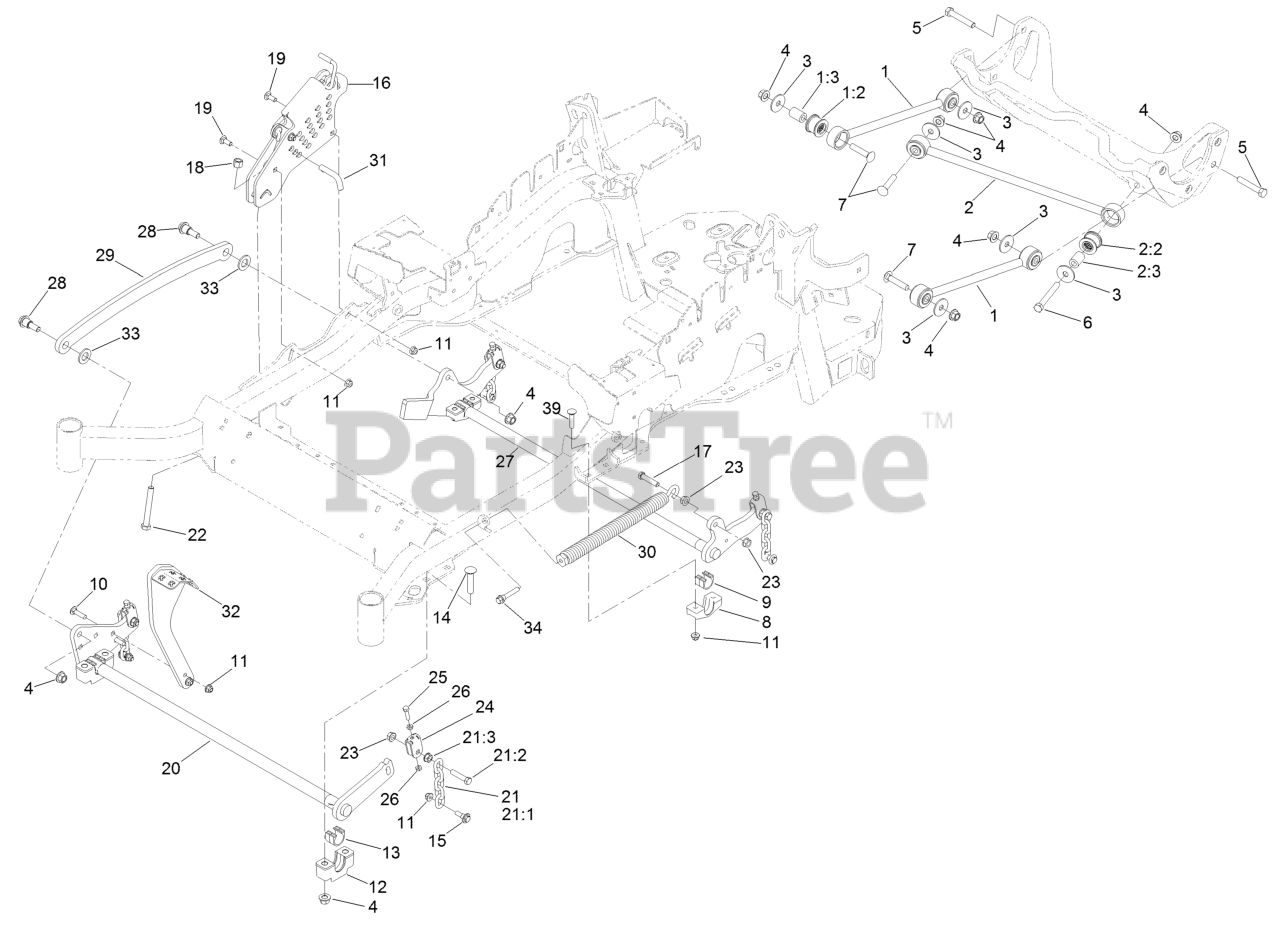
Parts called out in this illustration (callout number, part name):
1	DECK STRUT ASM
1:2	BUSHING-SUSPENSION, RUBBER
2	PANHARD ROD ASM
2:2	BUSHING-SUSPENSION, RUBBER
3	WASHER-THRUST
4	Nut-Lock 1/2-13
5	SCREW-HH
6	SCREW-HH
7	SCREW-CARR
9	BEARING-CROSS SHAFT, REAR
10	SCREW-CARR
11	NUT-HF, NI
12	SUPPORT-CROSS SHAFT, BEARING
13	BEARING-CROSS SHAFT, FRON
14	Bolt-Carriage 1/2-13 X 2 1/2 Spl Neck
15	SCREW-SHOULDER, HHF
16	HOC ASM
17	SCREW-HH
18	NUT-LOCK, NI
19	BOLT-CARR
20	DECKLIFT-FRONT
21	DECK LIFT CHAIN ASM
21:1	CHAIN-LIFT, DECK
21:2	SCREW-HH
22	BOLT-TAP
24	YOKE-ADJUST, DECK
25	SCREW-HH
26	NUT-JAM
27	LIFT-DECK, REAR
28	SCREW-SHOULDER, HHF 1/2-13 X 1.12
29	LINK-LIFT, DECK
30	SPRING-EXTENSION
31	PIN-HOC
32	LEVER-FOOT
33	WASHER-FLAT
34	BOLT-SHOULDER
39	SCREW-CARR
